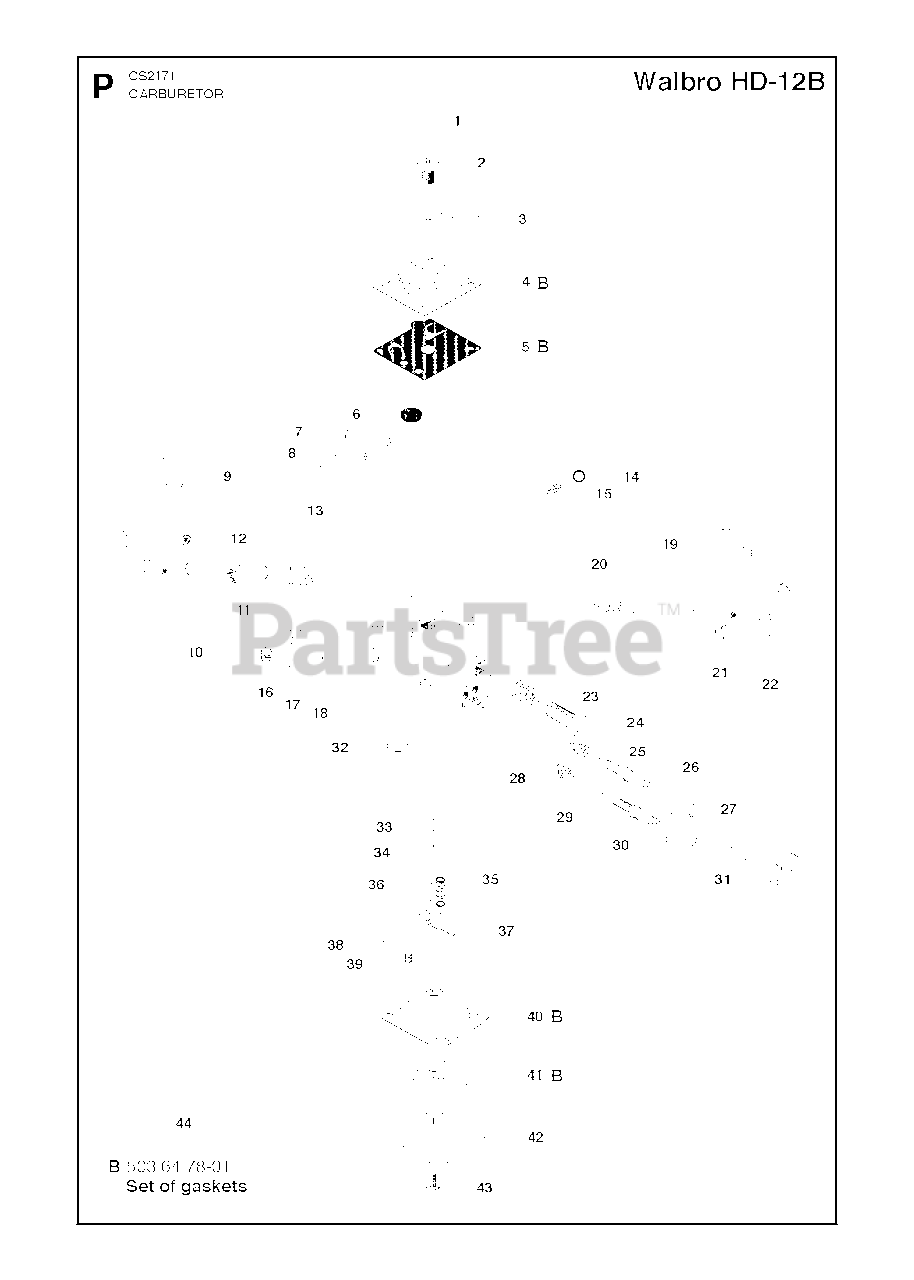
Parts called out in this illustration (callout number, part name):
1	CARBURETOR HD-12B EPA WALBRO
4	GASKET, PUMP SIDE
5	PUMP DIAPHRAGM
6	FUEL INLET SCREEN
7	RP NIPPLE
9	CHOKE FLAP
10	CHOKE SHAFT
11	LEVER
19	THROTTLE FLAP
21	SCREW SHUTTERS
26	ADJUSTING SCREW
27	LIMITER CAP
29	ADJUSTING SCREW
30	LIMITER CAP
32	WELCH PLUG
36	INLET NEEDLE
38	FULCRUM PIN
40	GASKET
41	GASKET
42	IMPULSE COVER
43	SCREW W/ WASHER
44	GASKET SET
